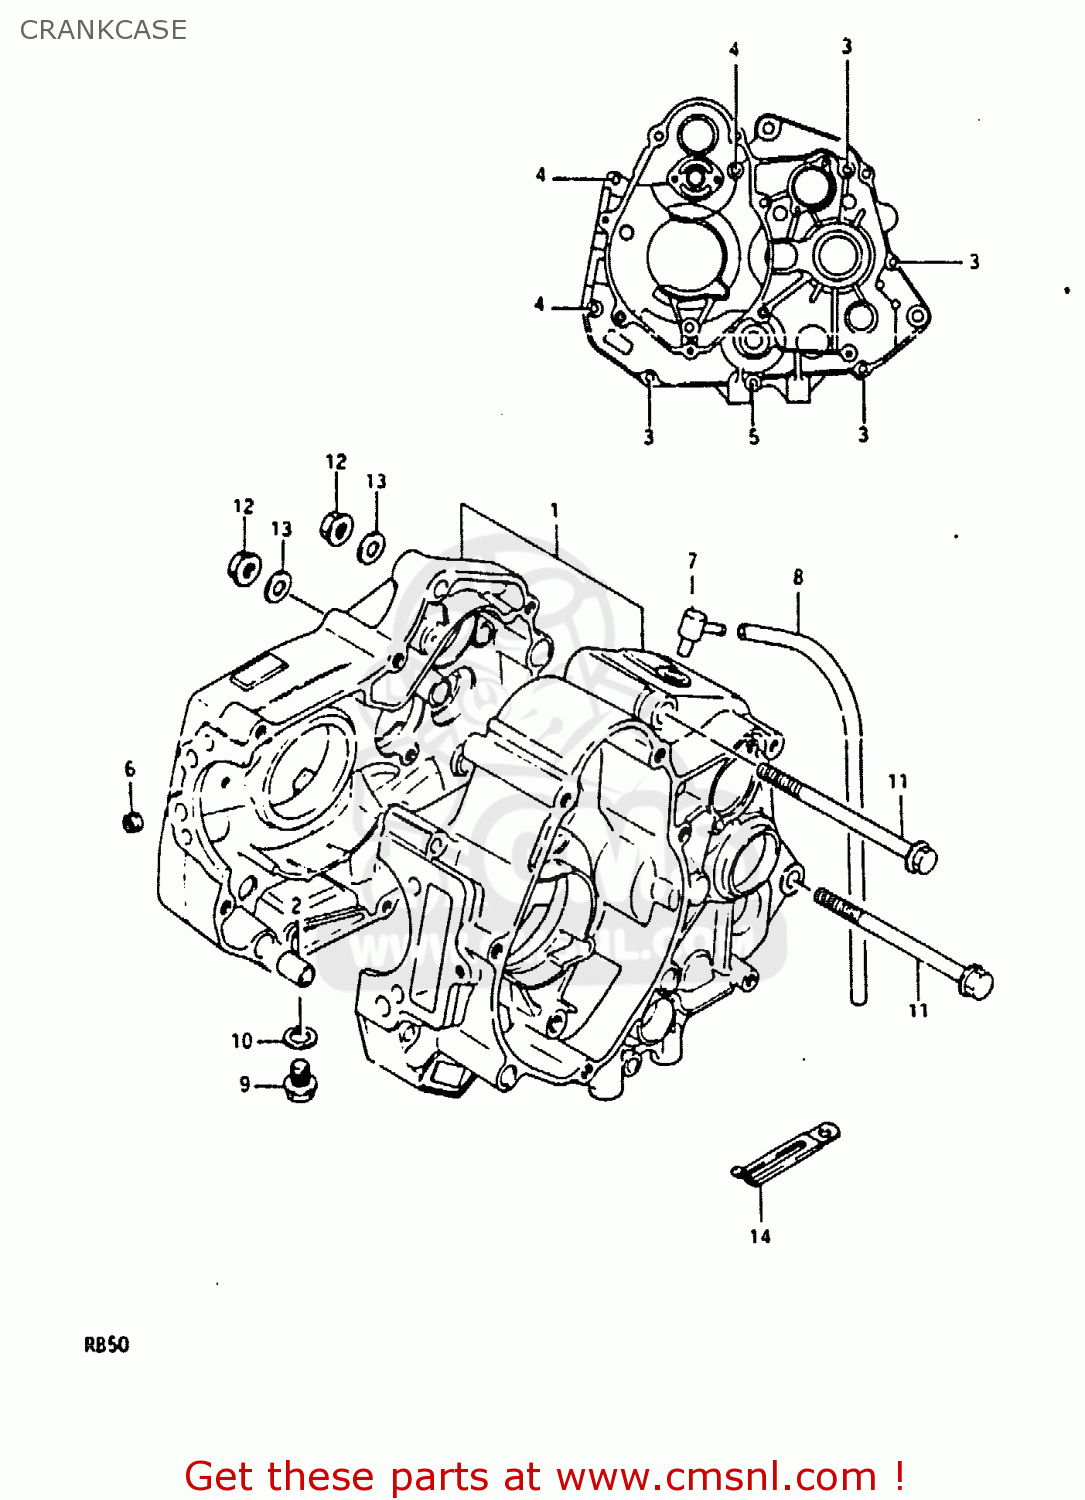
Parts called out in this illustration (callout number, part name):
1	CRANKCASE SET
2	PIN
3	SCREW 6X30
4	SCREW
5	CROSS SCREW (6 X 75)
6	PLATE,OIL JET
7	UNION,BREATHER HOSE
8	HOSE
9	PLUG
10	GASKET(10X14X3.6) (NAS)
11	BOLT(8X100)
12	NUT
13	WASHER
14	CLAMP L:35
